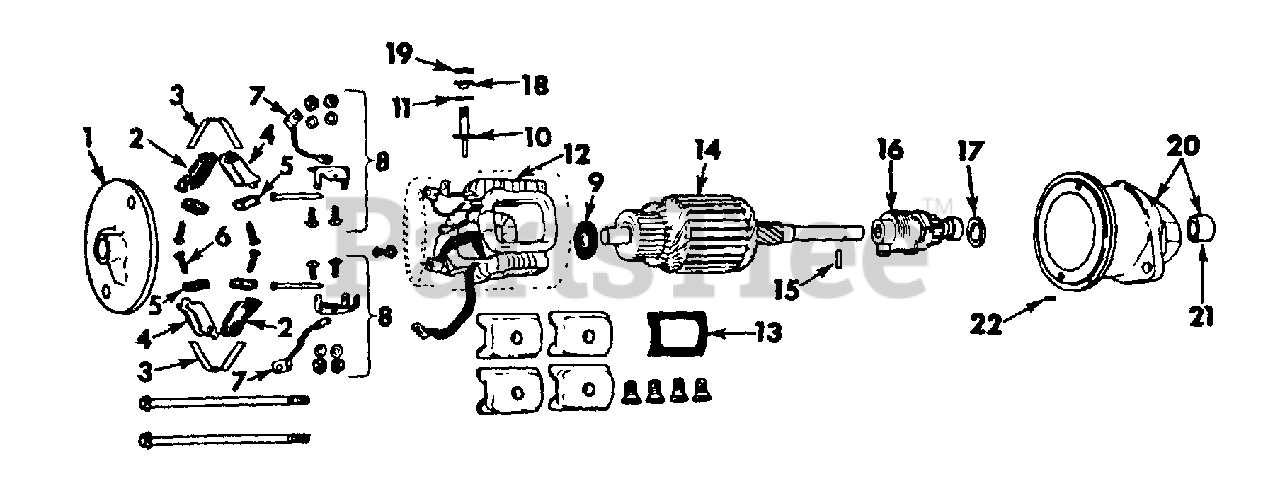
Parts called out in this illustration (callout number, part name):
1	FRAME, COMMUTATOR END
2	HOLDER, INSULATED BRUSH
3	SPRING, BRUSH
4	HOLDER, GROUND BRUSH
6	SCREW, BRUSH ATTACHING
7	LEAD, BRUSH GROUND
8	KIT, BRUSH HOLDER SUPPORT
9	WASHER, COMMUTATOR END BRAKE
10	STUD, TERMINAL
11	WASHER, INSULATED TERMINAL STUD
12	COIL ASSY, FIELD 4 COILS
13	INSULATION, FIELD COIL
15	PIN, ARMATURE SHAFT
16	DRIVE ASSY, MOTOR
17	WASHER, DRIVE END SPACE
18	BUSHING, INSULATED TERMINAL STUD
19	WASHER, INSULATED TERMINAL STUD
20	HOUSING ASSY, DRIVE END
21	BUSHING, DRIVE END HOUSING
22	PIN, DRIVE END DOWEL
